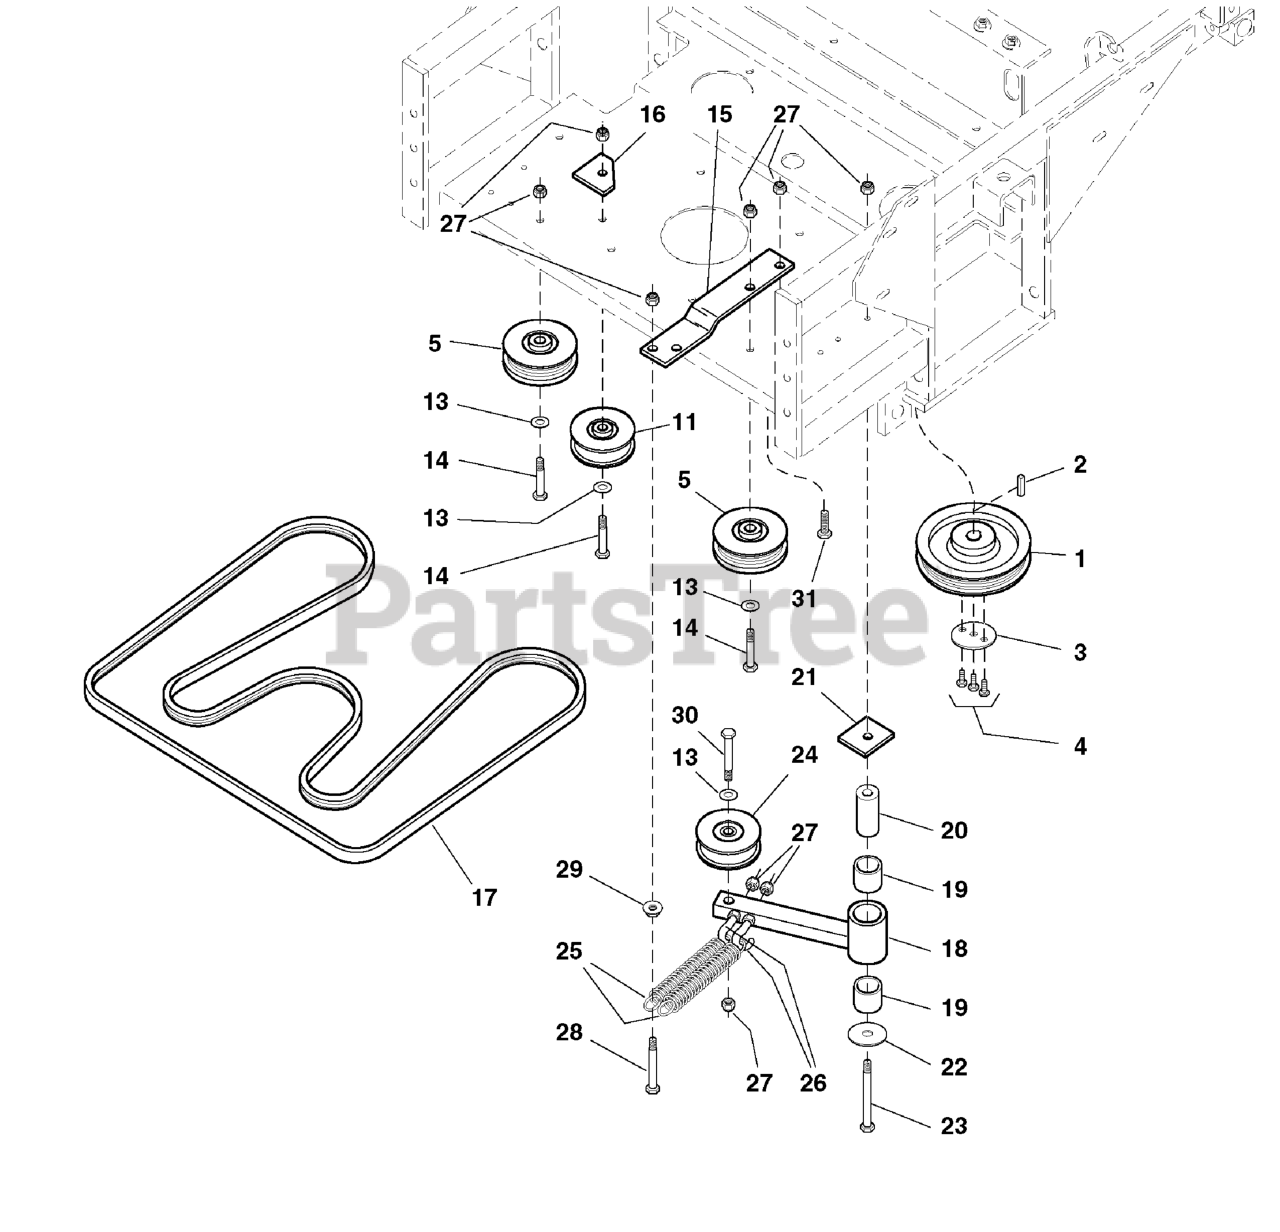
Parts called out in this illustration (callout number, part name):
1	PULLEY, Pump Drive
2	KEY, 5MM SQ. x 25MM w/ Round Ends
3	WASHER, Pulley Retaining
4	BOLT, M6 x 10MM
5	IDLER PULLEY ASSEMBLY
6	BEARING, BALL 11/16X1-9/16X15/32
7	SNAP RING, Internal
8	INSERT, Bearing
9	INSERT, Bearing, Shoulder
10	PULLEY, Idler
11	BACKSIDE IDLER PULLEY ASSEMBLY
12	PULLEY, Backside Idler
13	WASHER, 3/8 SAE
14	BOLT, 3/8-16 X 2-1/4" GD5 CZ
15	SPRING ANCHOR
16	SUPPORT, Pulley
17	BELT, Pump Drive
18	IDLER ARM ASSEMBLY, Complete
19	BUSHING, Brass
20	SPACER, .39 X 1.00 X 2.55, SS
21	SPACER, Idler Pivot
22	WASHER, 3/8 x 1-3/4
23	BOLT, 3/8-16 X 4" GD5 CZ
24	HYDRO IDLER PULLEY ASSEMBLY
25	SPRING, Extension
26	SCREW HOOK
27	NUT, 3/8-16 HEX NYLON LOCK
28	BOLT, 3/8-16 X 2-1/2" GD5 CZ
29	NUT, 3/8-16 Hex Serrated Flange
30	BOLT, 3/8-16 X 2-3/4" GD5 CZ
31	BOLT, 3/8-16 X 1" GD5 CZ
